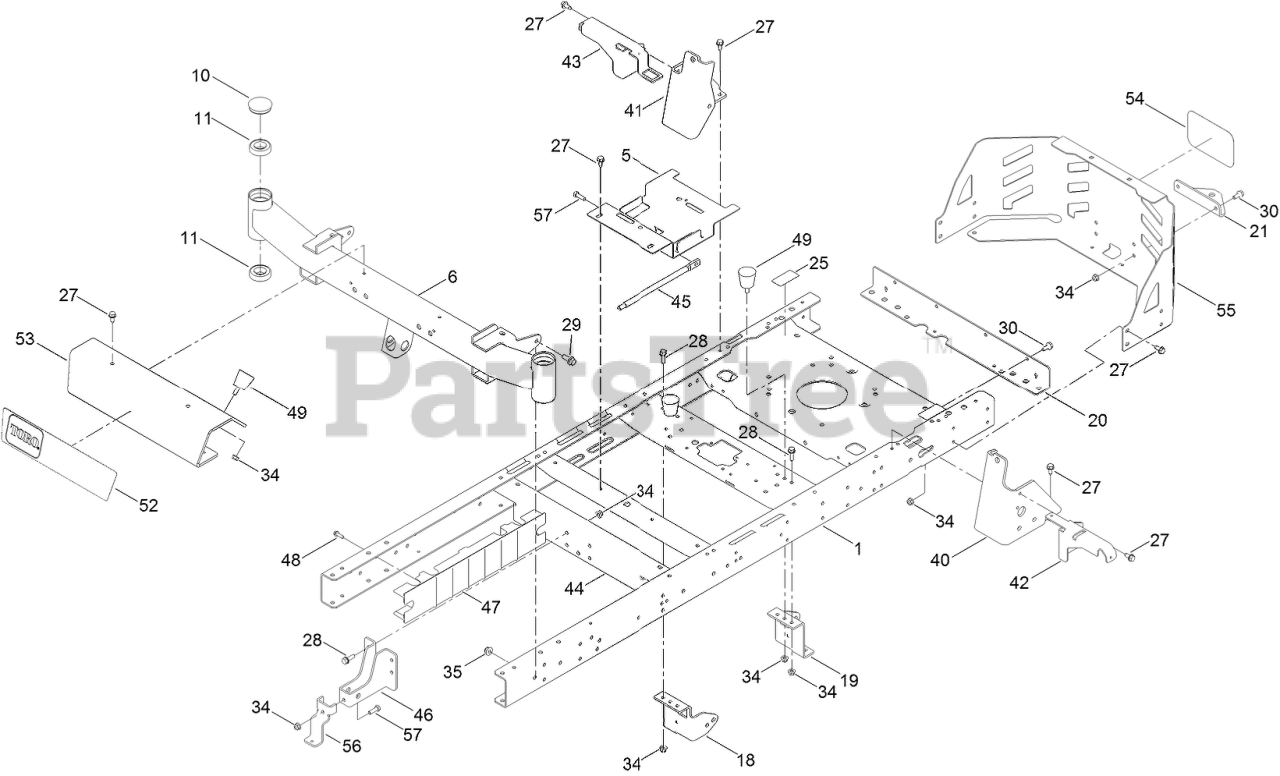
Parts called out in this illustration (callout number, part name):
1	FRAME ASM
5	BRACKET-BATTERY
6	AXLE-WIDE
10	CAP-GREASE
11	BEARING-BALL
18	MOUNT-HYDRO, FRONT (RIGHT)
19	MOUNT-HYDRO, FRONT (LEFT)
20	CROSSMEMBER-REAR, WIDE
21	BRACKET-HITCH
25	DECAL-BYPASS
27	SCREW-HWHTF
28	SCREW-HHF
29	SCREW-HHF
30	SCREW-HHF
34	NUT-HF, NI
35	NUT-HF, NI
40	BRACKET-MOUNT
41	BRACKET-MOUNT
42	SUPPORT-POD
43	SUPPORT-POD
44	BRACE-CROSS, LOWER
45	ROD-BRACE
46	BRACKET-MOUNT DAMPER, LOWER
47	GUARD-RAIL
48	SCREW-HWH
49	BUMPER-RUBBER
52	DECAL-TIMECUTTER
53	STEP-FRONT
54	DECAL
55	GUARD-ENGINE
56	STOP-DECK
57	SCREW-HH
